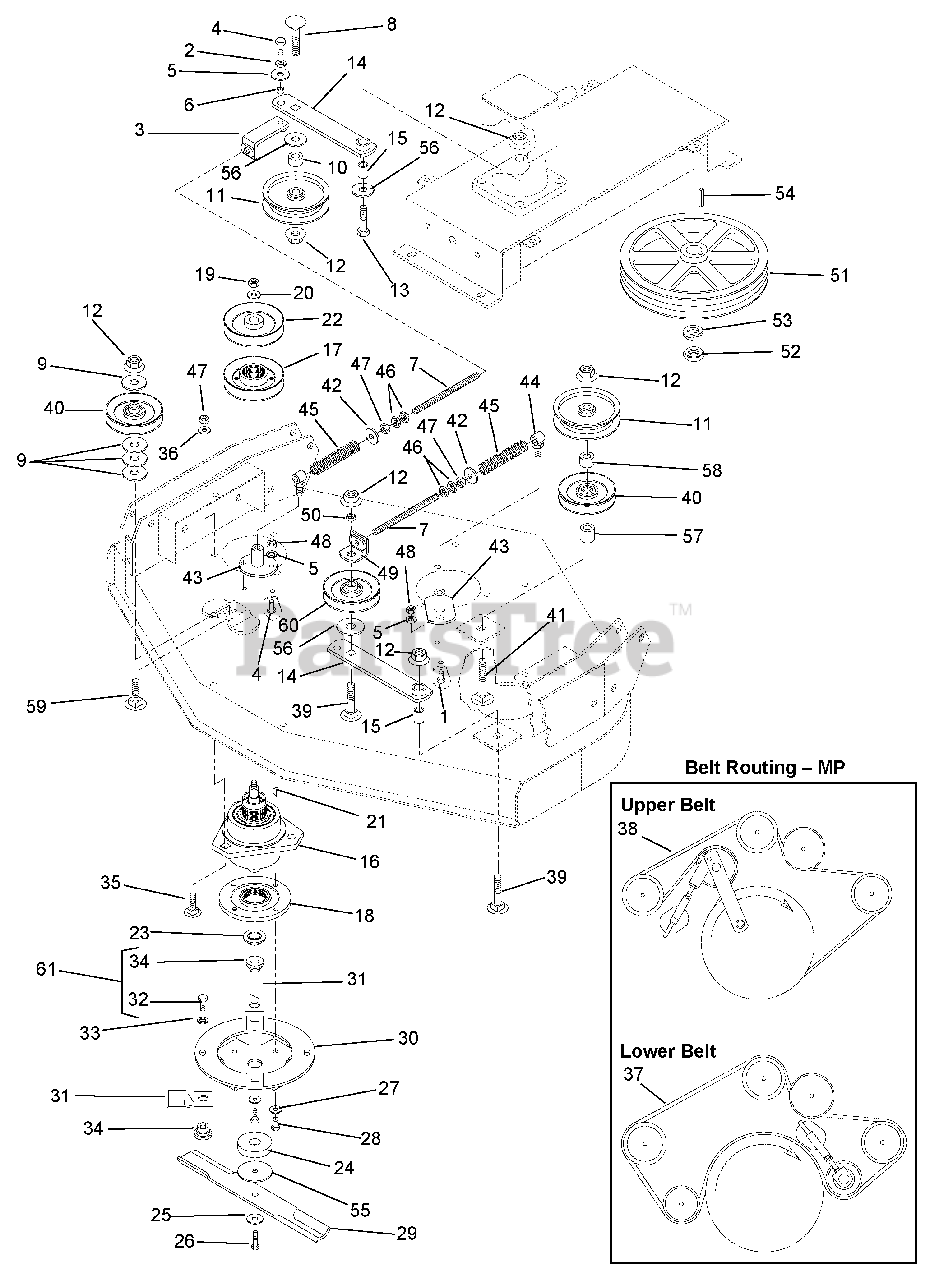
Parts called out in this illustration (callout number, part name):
1	Cap Screw, Hex Head .38-16 x 1
2	Washer, Lock .38
3	Weldment, Adjustment Rod
4	Cap Screw, Hex Head .38-16 x 1.25
5	Washer, Flat .38
7	Rod, Threaded
8	Bolt, Carriage .625-11 x 3
9	Washer, Flat 1.125
10	Spacer .69
11	Assembly, Idler
12	Nut, Flange Lock .625-11
13	Bolt, Pivot
14	Weldment, Idler Arm
15	Sleeve, Pivot
16	Spindle Assembly (Includes items 17 – 22)
17	Sheave, Lower
18	Carrier, Blade
19	Nut, Lock .625-11
20	Washer, Flat .325
21	Key, Woodruff #606
22	Sheave 5.50 EOD
23	Bushing, Blade
24	Washer, Blade
25	Washer, Heavy Duty Safety
26	Cap Screw, Hex Head .50-20 x 1.75
27	Washer, Belleville
28	Cap Screw, Hex Head .38-16 x .75
29	Blade, C.W.
30	Weldment, Disc
31	Blade, LH (each)
32	Cap Screw, Flanged .38 x .875
33	Washer, Flat .38 SAE
34	Nut, Blade
35	Bolt, Carriage .50-13 x 1.50
36	Washer, Lock .50
37	Belt, HBB 101.0
38	Belt, HB 115.0
39	Bolt, Carriage .625 x 2.50
40	Idler, V 5.5
41	Bolt, Carriage .625 x 4.5
42	Washer, Flat .50 USS
43	Weldment, Pivot Mount
44	Weldment, Pivot
45	Spring 1.10 O.D.
46	Nut, Jam .50-13
47	Nut, Hex .50 CP
48	Nut, Hex .38-16
49	Weldment, Pivot Angle
51	Sheave, Machined 15.16 Diameter
52	Nut, Hex M30 x 2
53	Washer, Spring Outer Tooth
54	Key 6mm x 6mm x 30mm
56	Washer, Flat .625 SAE
57	Spacer, Idler Long
58	Spacer, Idler Short
59	Bolt, Carriage .625 x 2
60	Idler, V 4.7 E.O.D.
61	Blade Nut and Bolt Kit (Includes 40 each of item 32 and 40 each of item 34)
